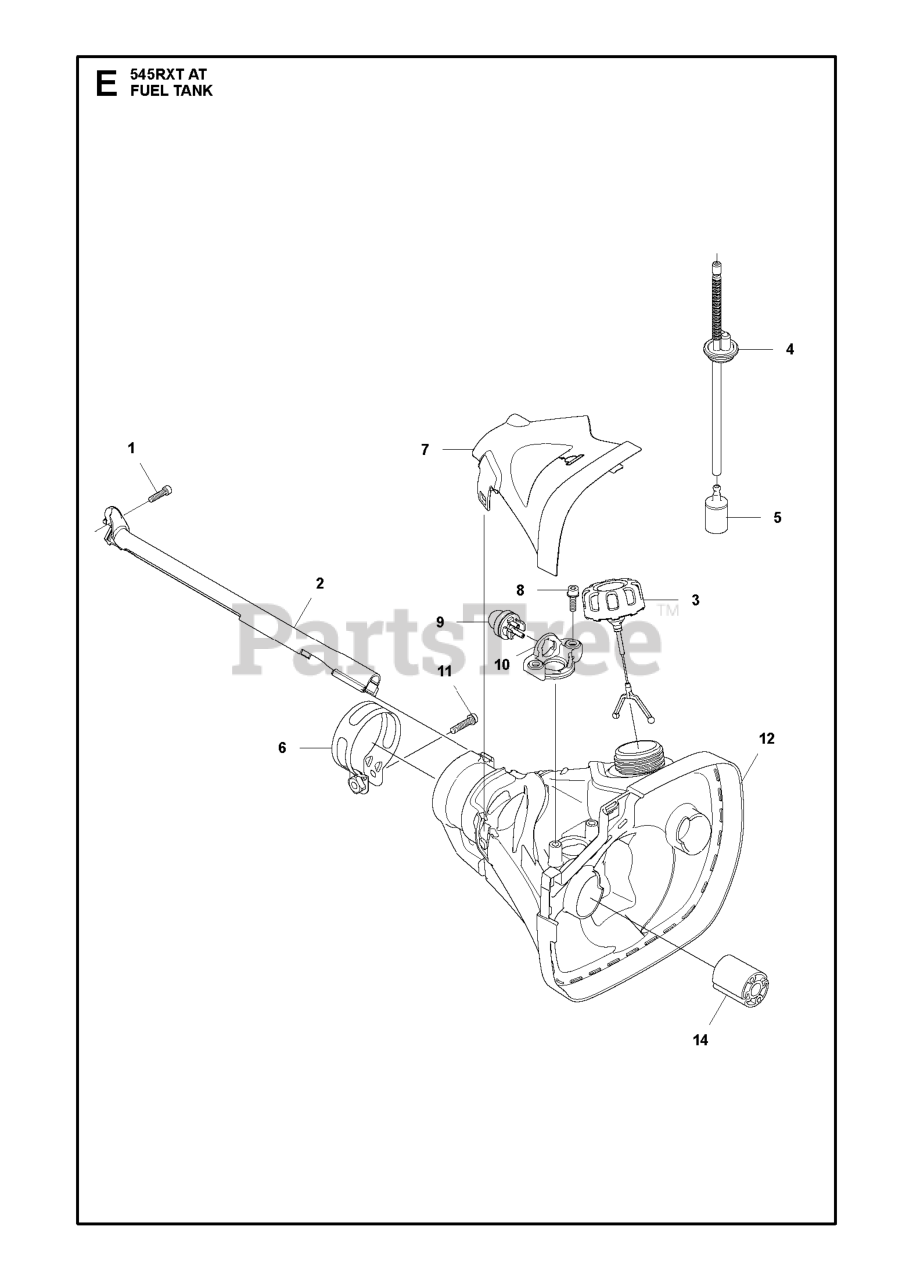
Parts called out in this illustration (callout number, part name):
5	RP FUEL FILTER
6	CLAMP ASSY
7	COVER LID FUEL TANK HVA
9	AIR PURGE BUBBLE
11	SCREW IHSCFM
12	FUEL TANK ASSY HVA
14	ANTIVIBRATION ELEMENT
